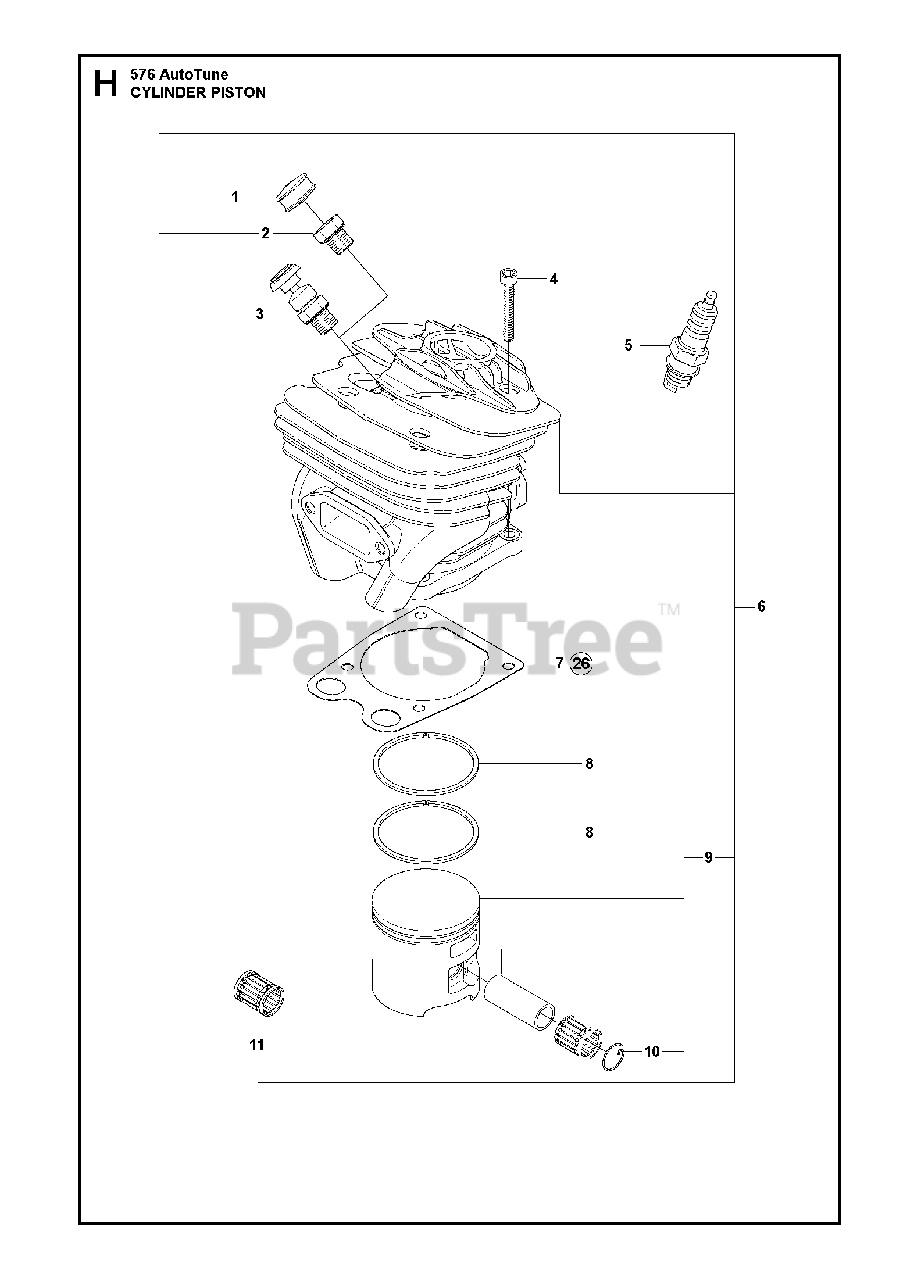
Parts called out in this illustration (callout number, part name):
1	PLUG
2	CYLINDER PLUG
3	VALVE
4	SCREW MC6S 5X25
5	BPMR7A NGK SPARK PLUG
6	CYLINDER ASSY
7	GASKET
8	%PISTON RING
9	PISTON ASSY
10	WRIST PIN CLIP
11	SUPPORT BUSHING
26	GASKET KIT
